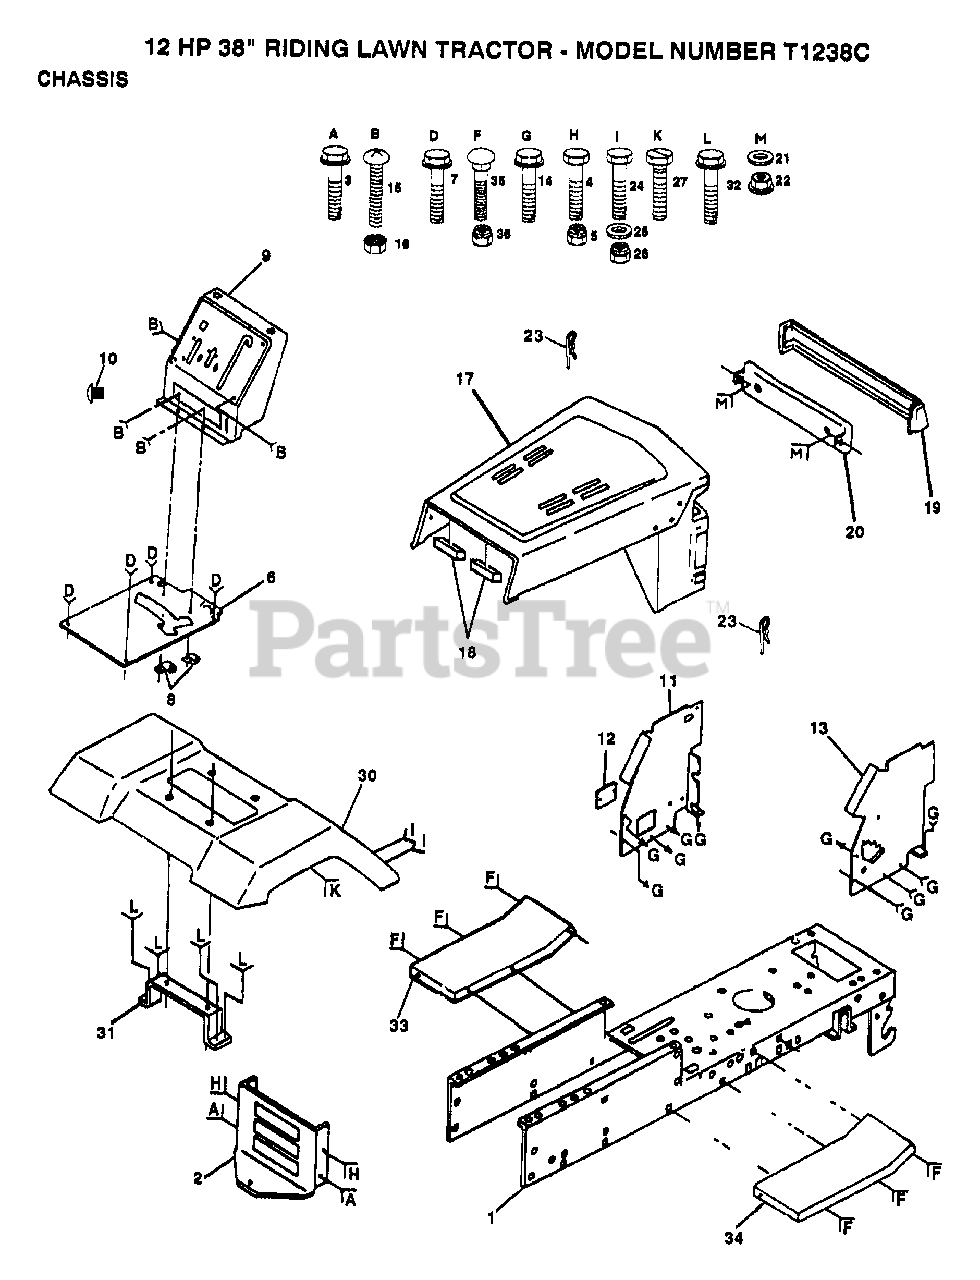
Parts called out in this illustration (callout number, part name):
1	CHASSIS WELDMENT
2	DRAWBAR LT/YT
3	SCREW
7	SCREW LT
8	CLIP T
10	PLUG BUTTON T
11	PANEL DASH LH
12	COVER ACCESS
14	SCREW LT
15	SCREW
17	HOOD/GRILL ASM
21	WASHER PM
22	PAL NUT LT
23	SPRING.RETAINER
25	WASHER
27	SCREW LT
32	SCREW
33	FOOTREST LH
34	FOOTREST
35	BOLT
